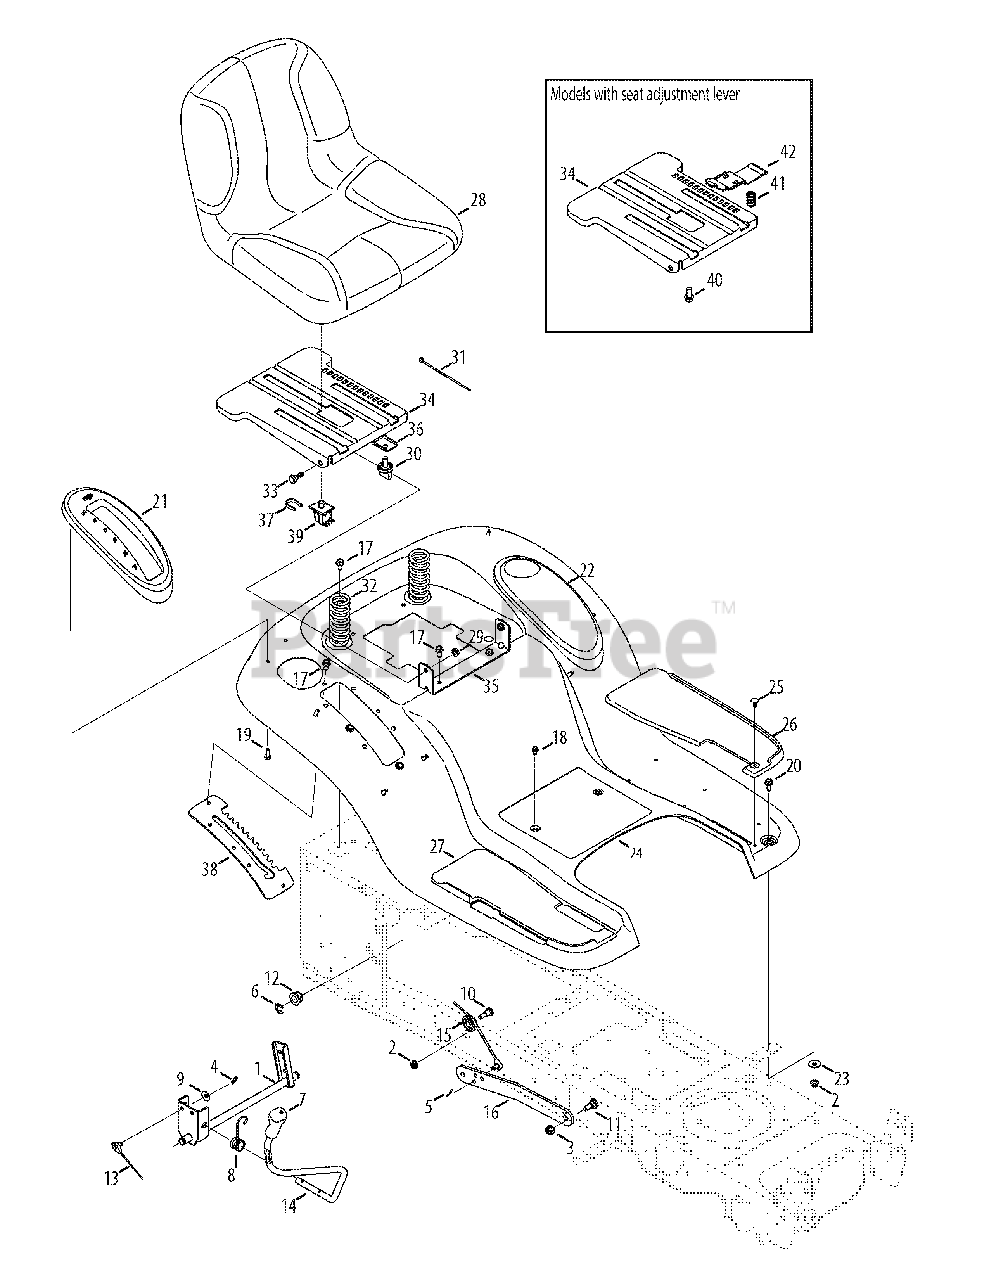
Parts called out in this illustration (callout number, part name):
1	Lift Shaft Assembly
2	Flangelock Nut, 5/16-18
3	Flangelock Nut, 3/8-16
4	Cotter Pin, .072 DIA. x 1.13 LG
5	Bow-Tie Cotter Pin
6	E-Ring, .625 DIA. SHAFT
7	Handle Grip
8	Torsion Spring
9	Spring Washer, .401 x .870 x .063
10	Shoulder Screw, .437 x .470:5/16-18
11	Shoulder Bolt, .500 x .270:3/8-16
12	Hex Flange Bearing
13	Lift Cable, 16.16 LG
14	Lift Handle
15	Pulley Roller Cable
17	Taptite Screw, Lock Washer, 5/16-18
18	Taptite Screw, Lock Washer, 1/4-20
19	Hi-Lo Screw, Lock Washer, 1/4-15
20	Taptite Screw, 5/16-18:.750
21	Lift Lever Cover
22	Cover with Cup Holder
23	Flat Washer, .344 x 1.00 x .063 HDN
25	Ratchet Clip
26	LH Foot Pad
27	RH Foot Pad
28	Seat
29	Flangelock Nut, 5/16-18
31	Cable Tie, 3/16 x .05 x 7.4
32	Compression Spring, 1.71 x 3.735 x .238
33	Shoulder Screw, .437 x .268:5/16-18
34	Seat Mounting Bracket
35	Seat Pivot Bracket
36	Knob Adjust Bracket
37	Switch Retainer Clip
38	Lift Bracket, 5 Style
39	Seat Switch
40	Hex Head Flange, 3/8-16:.875
41	Compression Spring, .68 x 1.065 x .055
42	Seat Adjustment Lever
